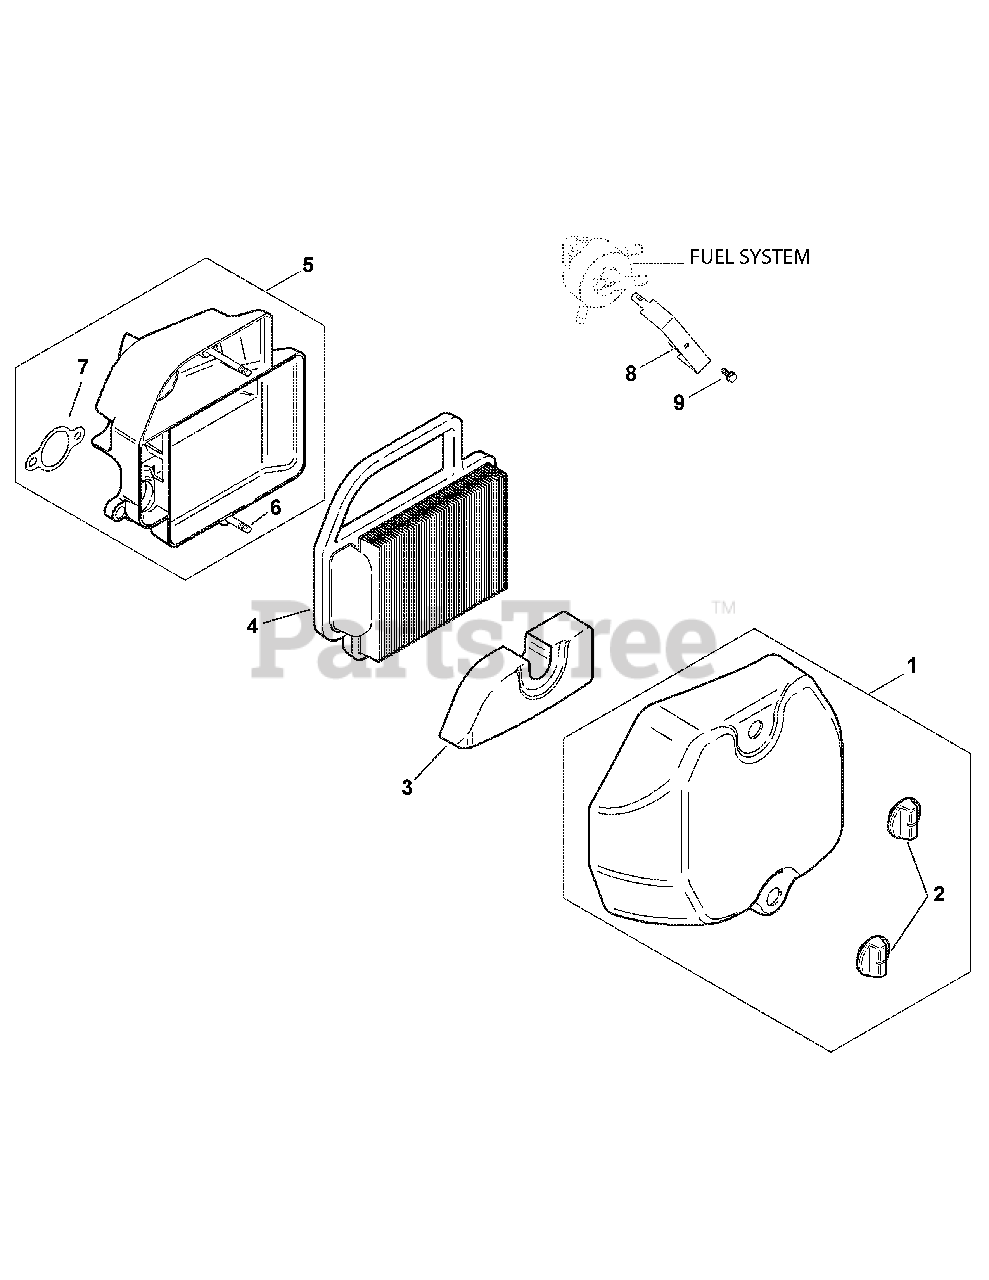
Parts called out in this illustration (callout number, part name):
1	Air Cleaner Cover Kit
3	Pre-Cleaner Element (Dry)
4	Air Cleaner Element
5	Air Cleaner Base Kit
6	Air Cleaner Base Stud
7	Air Cleaner Base Gasket
8	Fuse Block
9	Fuse Block
